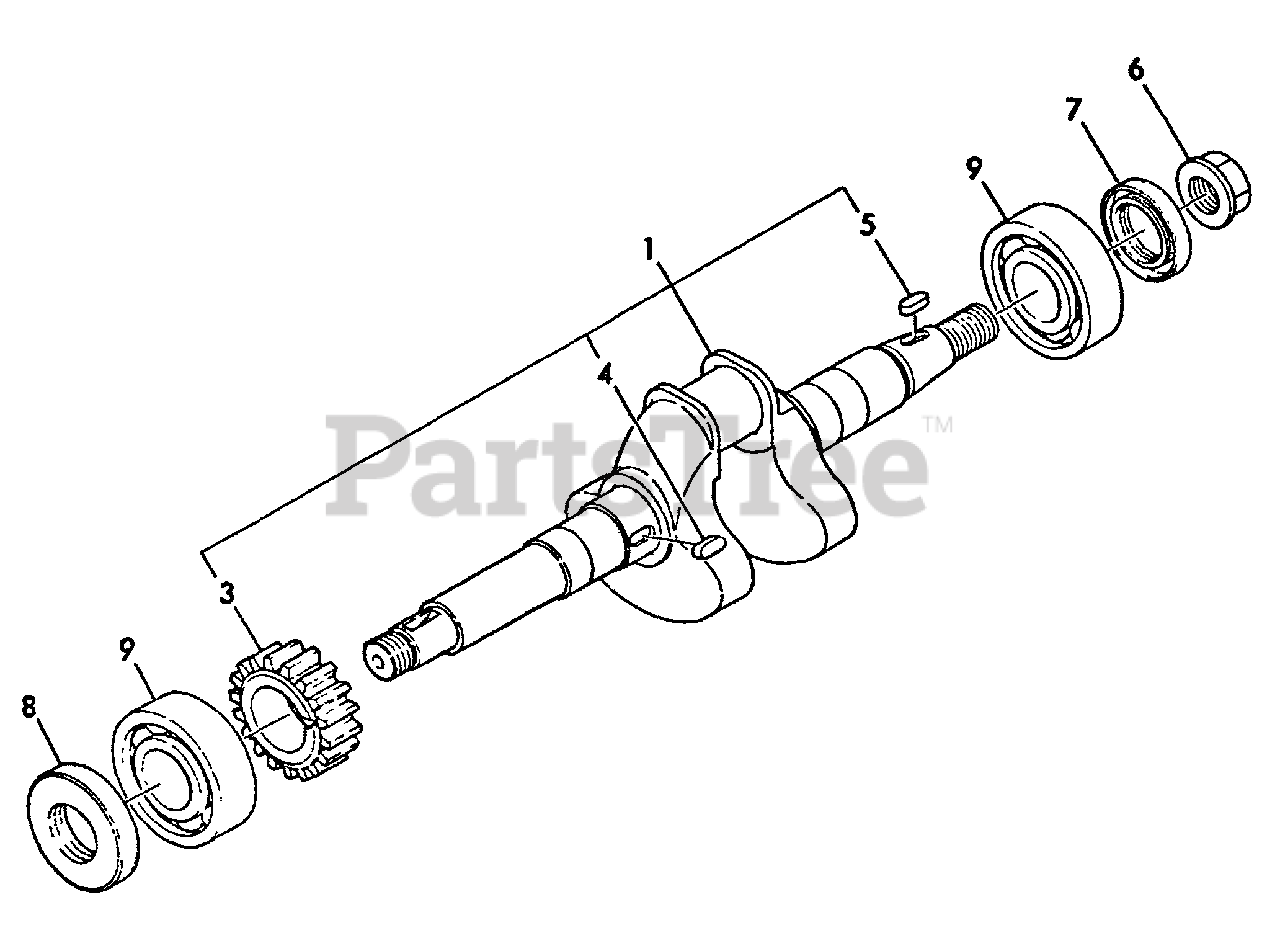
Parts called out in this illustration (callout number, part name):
1	CRANKSHAFT ASSY
3	GEAR, CRANKSHAFT
4	KEY - 4×10
5	KEY - 4×10
6	NUT - 12
7	SEAL, OIL
8	SEAL, OIL
9	BEARING, BALL 6204 C3
